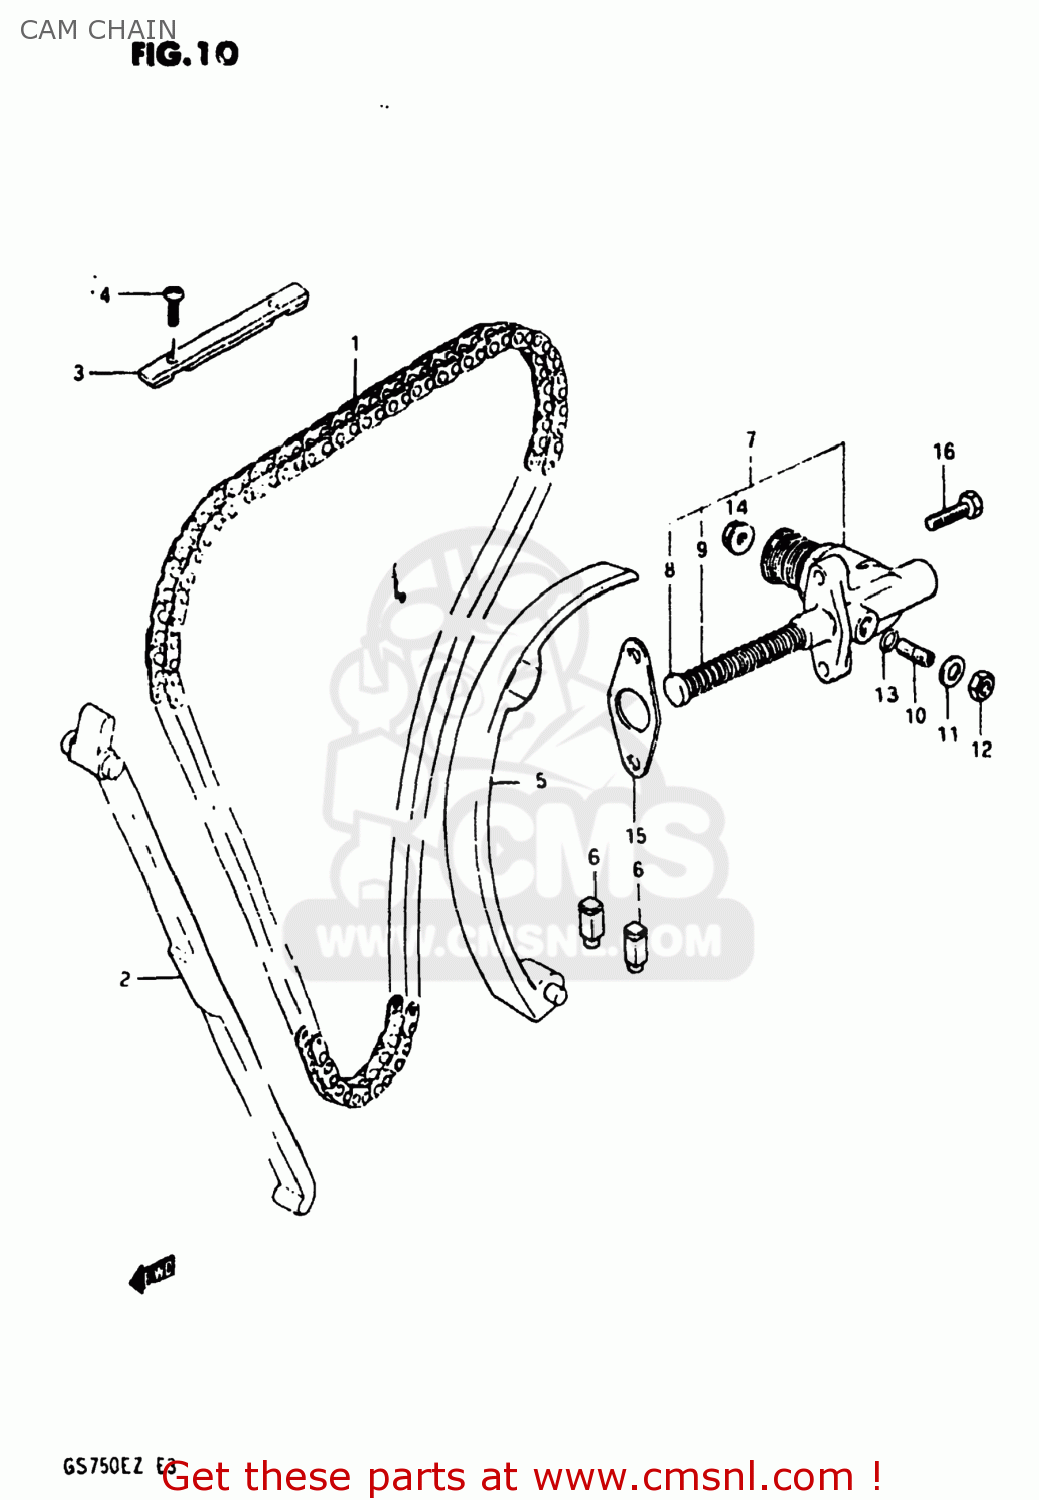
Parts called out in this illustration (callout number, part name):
1	CHAIN,CAMSHAFT DRIVE
2	GUIDE,CAM CHAIN NO.1
3	GUIDE,CAM CHAIN NO.3
4	SCREW
5	TENSIONER,CAM CHAIN
6	CUSHION,CAM CHAIN TENSIONER
7	ADJUSTER ASSEMBLY,TENSIONER
8	ROD,PUSH
9	SPRING
10	SCREW
11	WASHER
12	NUT
13	O-RING
14	NUT
15	GASKET,TENSIONER ADJUSTER (MCA)
16	SCREW (6X25)
